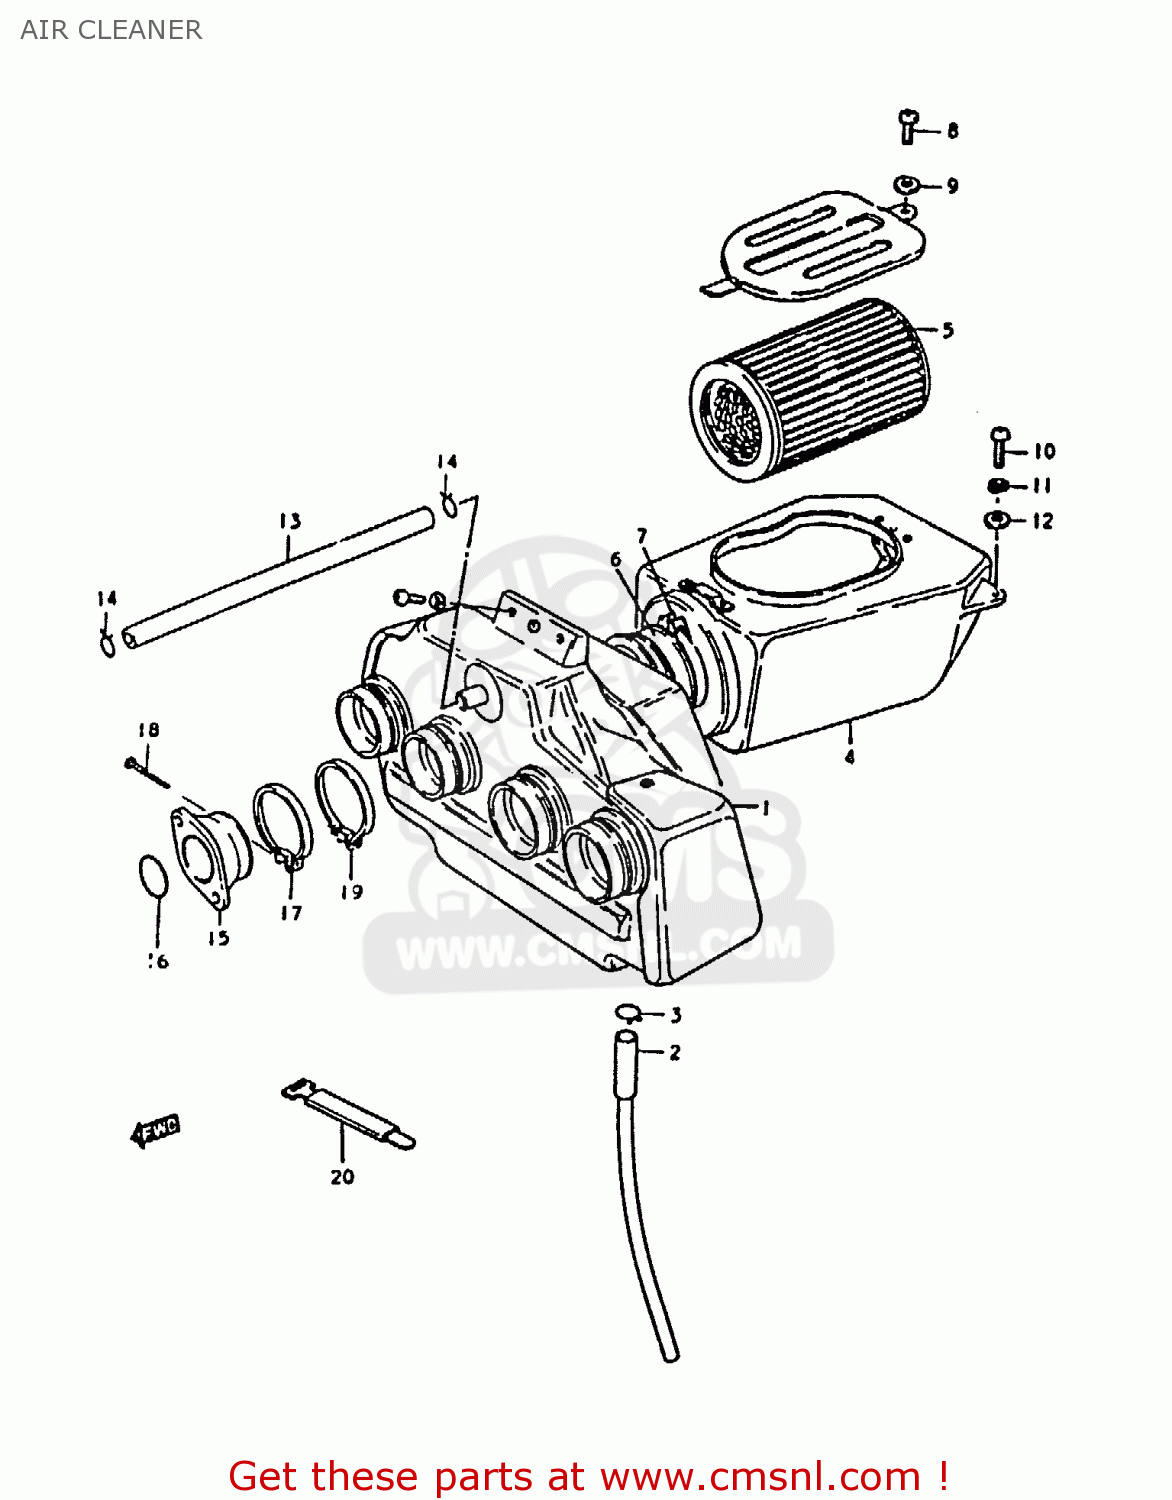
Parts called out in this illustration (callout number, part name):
1	CASE,AIR CLEANER,FRONT
2	HOLDER,FILTER
3	HOSE,AIR CLEANER
4	CASE ASSEMBLY,AIR CLEANER
5	FILTER,AIR CLEANER
6	HOSE,AIR CLEANER
7	BAND
8	SCREW
9	WASHER
10	BOLT, UPPER
11	LOCK WASHER
12	WASHER
13	HOSE
14	CLIP
15	PIPE,INTAKE
16	O RING(D:2.4,ID:31.7)
17	CLAMP
18	SCREW
19	CLAMP
20	CLAMP(L:120)
